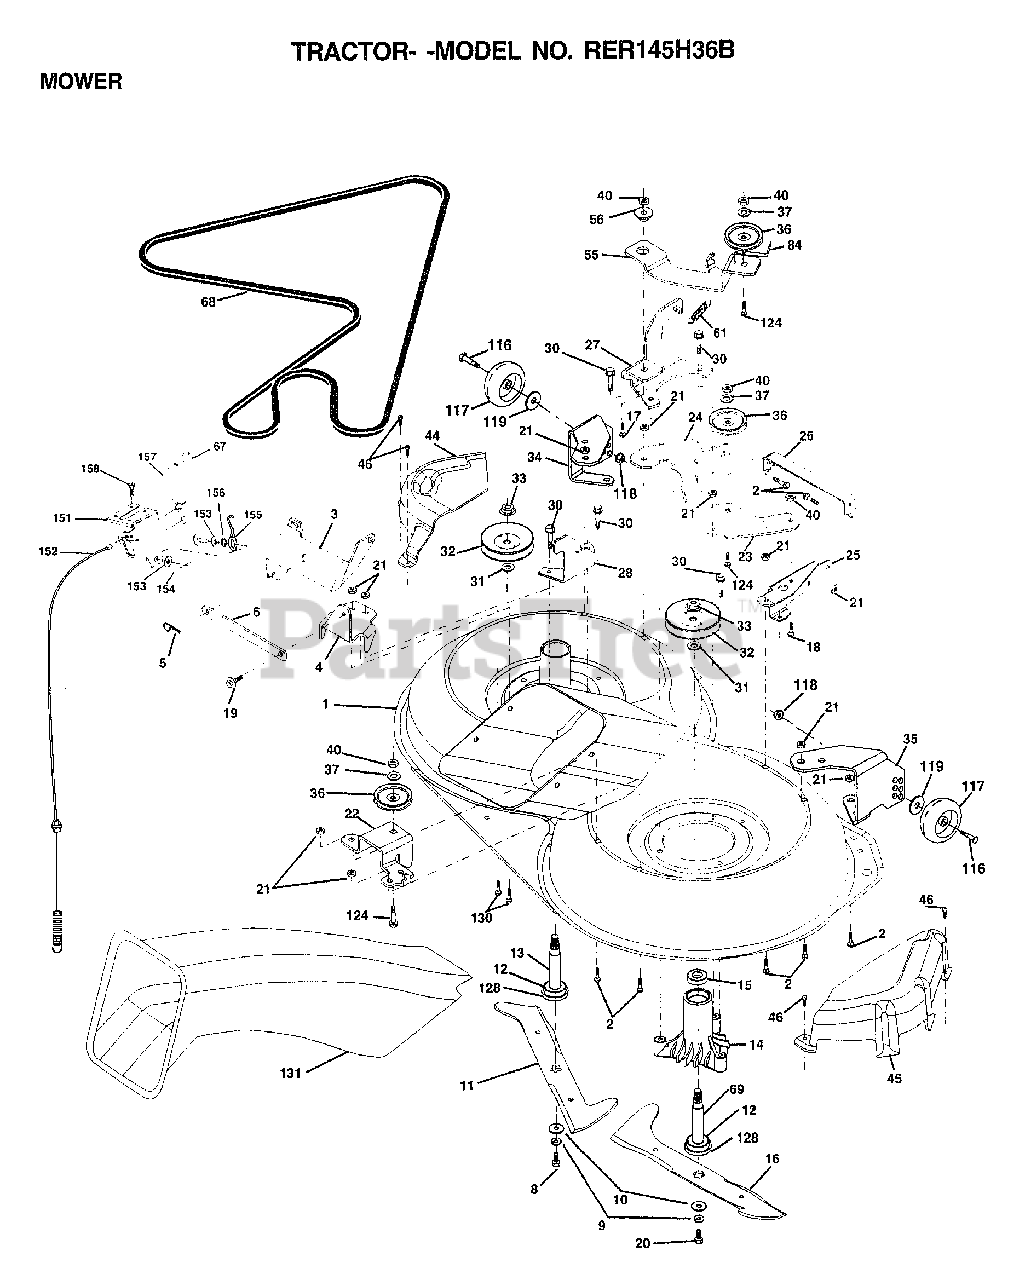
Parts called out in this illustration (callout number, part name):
1	HOUSING.ASM.MOWER
2	BOLT
3	BRKT.ASM.S-BAR.CHASSIS
4	BRKT.BAR.SWAY.DECK
6	BAR.SWAY.92.CRD
8	BLADE BOLT
10	WASHER.HARD.BLADE
11	BLADE
12	BEARING.BALL
14	HSG ASM MANDREL
15	BEARING
16	BLADE
17	BOLT.3/8-14X1.25
18	BOLT D
19	BOLT SHD 5/16-18
20	BOLT.3/8-24X1.25
22	BRKT.IDLER.SPRT.CRD
23	"BRKT.IDLER.SPRT.RF.92,CRD"
24	BRKT.SUSP.LF.92.CRD
25	BRKT.SUSP.RF.92.CRD
26	BRACE.SUPT.SUSP.FRT.CRD
27	BRKT.ASM.SUSP.RR.92.CRD
28	BRKT.ASM.SUSP.LR.92.CRD
30	"SCREW-THD ROLL,WA"
31	WASHER
32	PULLEY.MAND.36/46
34	BRKT.GUAGE.WHL.LF.92.CRD
35	BRKT.GUAGE.WHL.RF.92.CRD
36	PULLEY.IDLER.4.25
37	WASHER
44	COVER.MANDREL.LH.92.CRD
45	COVER.MANDREL.RH.92.CRD
46	SCREW.1/4-20X5/8
55	ARM.IDLER.92.CRD
56	SPACER.RETAINER.MOWER
61	SPRING.TENSION.BELT
67	KNOB T(3/8 HOLE)
68	HEX-BELT.92.MWR.105AA
69	SHAFT.ASM.W/LWR.BRG.RH.THD
84	"KEEPER-BELT,IDLER"
116	BOLT.SHOULDER
117	WHEEL GAGE DONUT
118	LOCKNUT
119	WASHER
124	BOLT.3/8-16X1.50
128	WASHER.FELT.
131	CHUTE.BAGGER.CRD
150	BRKT CLUTCH CABLE
152	CABLE CLUTCH CRD SERVICE
153	WASHER FLAT
154	SPRING RETAINER
155	SPRING RETENTION LVR CLUTCH CAB
156	SPACER
157	ROD.CLUTCH.CABLE.3/8
158	SCREW LT
